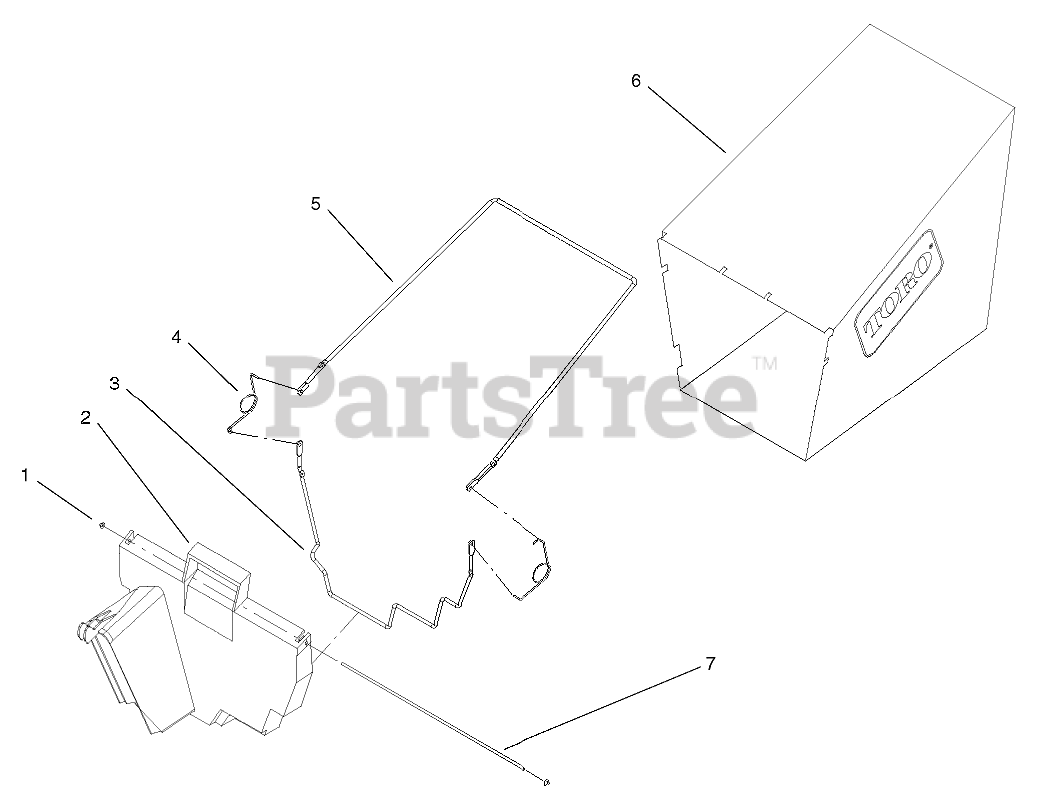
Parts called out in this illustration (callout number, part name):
1	NUT-PUSH
2	DOOR-BAG
3	FRAME-BAG
4	SPRING
5	FRAME-BAG, UPPER
6	Bag-Grass
7	HINGE-DOOR, BAG
